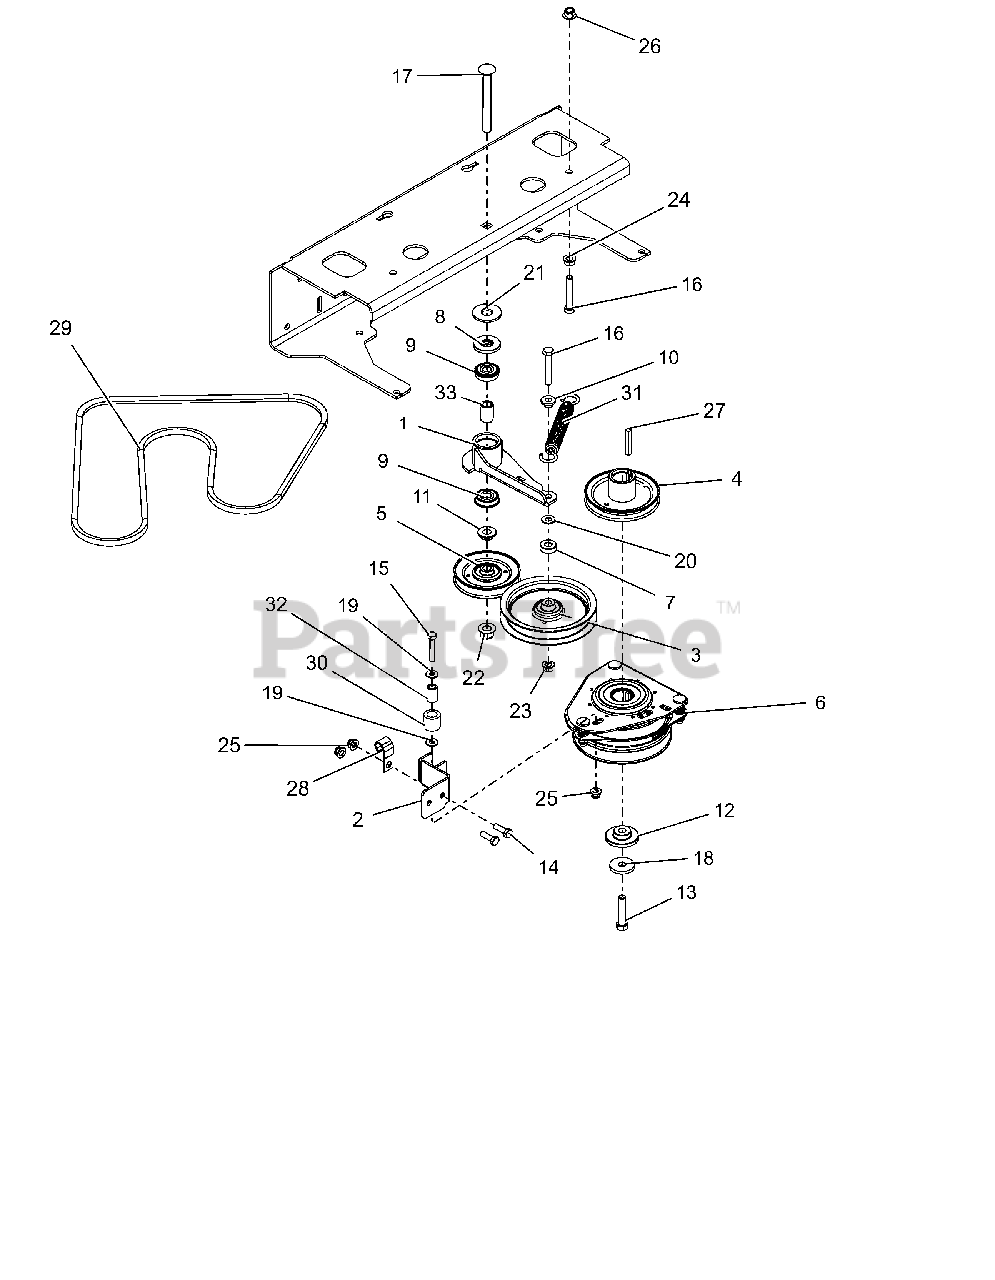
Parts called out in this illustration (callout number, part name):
1	WLDMT, IDLER ARM GROUND DRIVE
2	WLDMT, CLUTCH STOP
3	IDLER, FLAT-5.00X.75
4	SHEAVE, ENGINE 4.5 OD X 1.127
5	SHV, .50"ID X 4.00"OD V-IDLER
6	CLUTCH, OGURA GT1A-AR03
7	SPCR, .375 X 1.00 X .342
8	SPACER, IDLER ARM
9	BRG-BALL .50X1.38X.438 SEALED
10	BSHG-FLG .385X.500X.875X.406
11	BSHG, FLG .515X.750X.360X1.12
12	BSHG-FLG .469X1.06X.574X2.0
13	BLT-HEX .438-20X2 G8YZ NYTORQ
14	@BLT-HEX .31-18X1.00 GR5 YWZC
15	@BLT-HEX .31-18X1.75 GR5 YWZC
16	@BLT-HEX .38-16X2.25 GR5 YWZC
17	BLT-RDHDSQNK .50-13X4.50 G5 Y
18	WASHER, 7/16" SPRING DISK
19	@WSHR-FL-STL.312X.734X.065 YWZ
20	@WSHR-FL-STL.406X.812X.065 YWZ
21	@WSHR-FL-STL.688X1.75X.134 YWZ
22	@NUT-LK-NYL-FLG .50-13 YWZC
23	NUT-LK-CTR-FLG .38-16 YWZC
24	@NUT-SPNLK-FLG .375-16 YWZC
25	@NUT-LK-NYL-FLG .31-18 YWZC
26	@NUT-LK-NYL-FLG .38-16 YWZC
27	KEY-STR .25X1.75X.25
29	V-BELT, A-COGGED
30	BUMPER,RUBBER .62X1.0X.88 LG
31	SPRING, EXTENSION
32	BUSH.,S.391X.622X.950 ST
33	SPACER .510 X .75 X 1.1485
